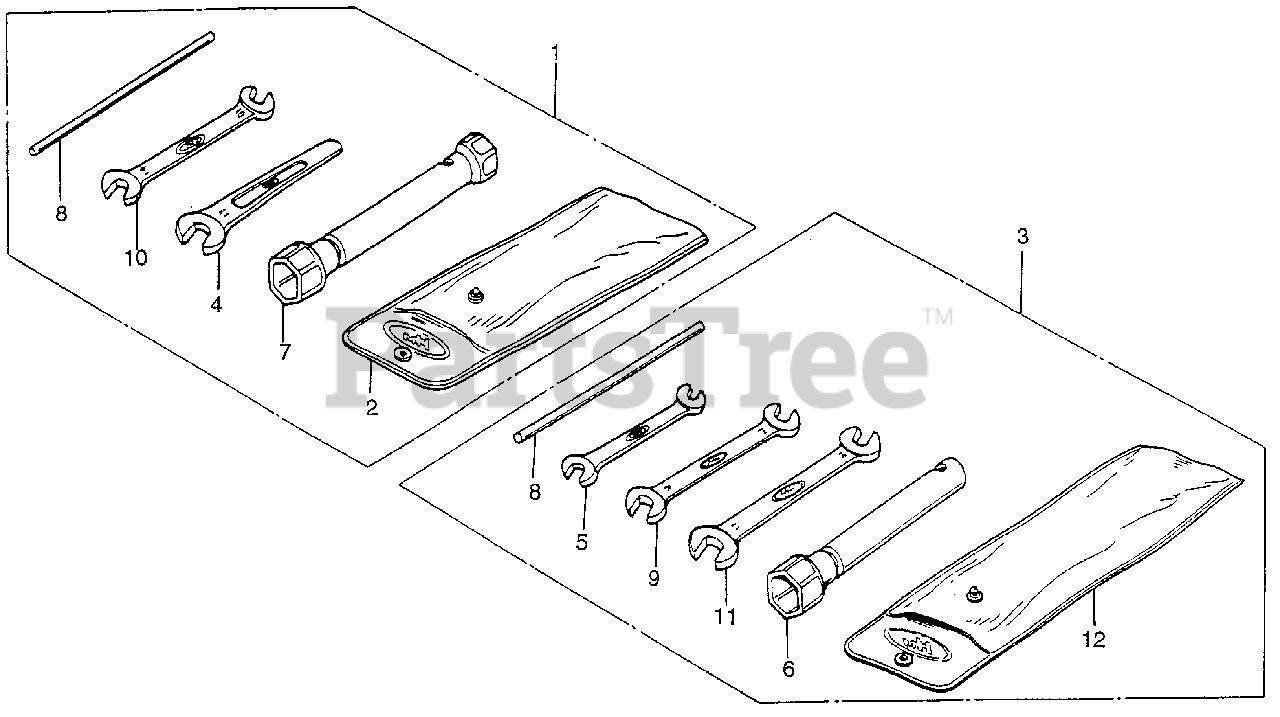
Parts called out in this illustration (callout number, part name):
1	TOOL SET (NOT AVAILABLE)
4	WRENCH OPEN END (7MM)
7	WRENCH, SPARK PLUG
8	HANDLE, BOX WRENCH
10	WRENCH (10X14) (OPEN END)
